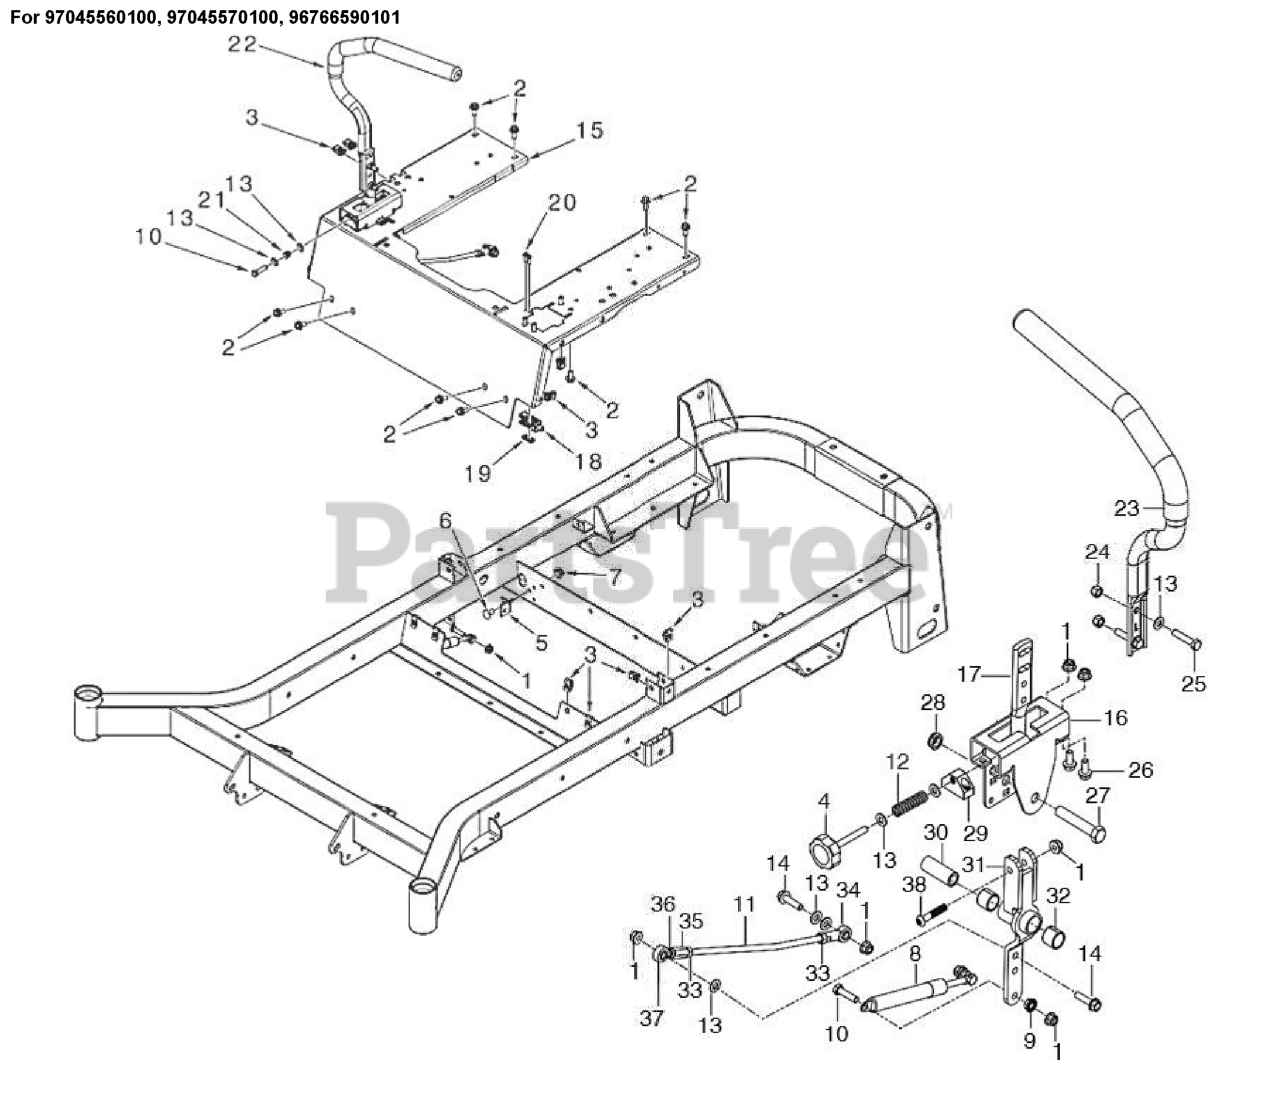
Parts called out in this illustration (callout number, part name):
1	NUT HEXAGON FLANGE 5/16-18 ST
3	U-CLIP 5/16-18 NUT RETAINER
5	BRACKET.DAMPENER.BLACK
9	GSPW Hardware
12	SPRING COMPRESSION 2.0
13	WASHER 11/32 X 11/16 X 14 GA T
15	SUPPORT.PNT.SEAT.CONTROL.ORNG
16	BRACKET.CONTROLS.ZTR.X431
17	LEVER.HANDLE MOUNT
18	SWITCH, INTERLOCK
20	SCR #10-24 X .75 SKT HD BLK
22	TUBE.LEVER.CONTROL.ZTR.RT.428
23	TUBE.LEVER.CONTROL.ZTR.LT.428
26	HHFS 5/16-18 X 3/4
28	NUT 1/2-13 HEX JM NYL
30	SPACER.PIVOT.CONTROL
31	CONTROL.WELDMENT.RZ
32	BEARING.PT.750
34	JOINT.HEIM.FEML.5/16.RH.THREAD
37	ROD.END.MALE.LH.THREAD
38	SCREW 5/16-18 X 1 3/4 BTN-HD
